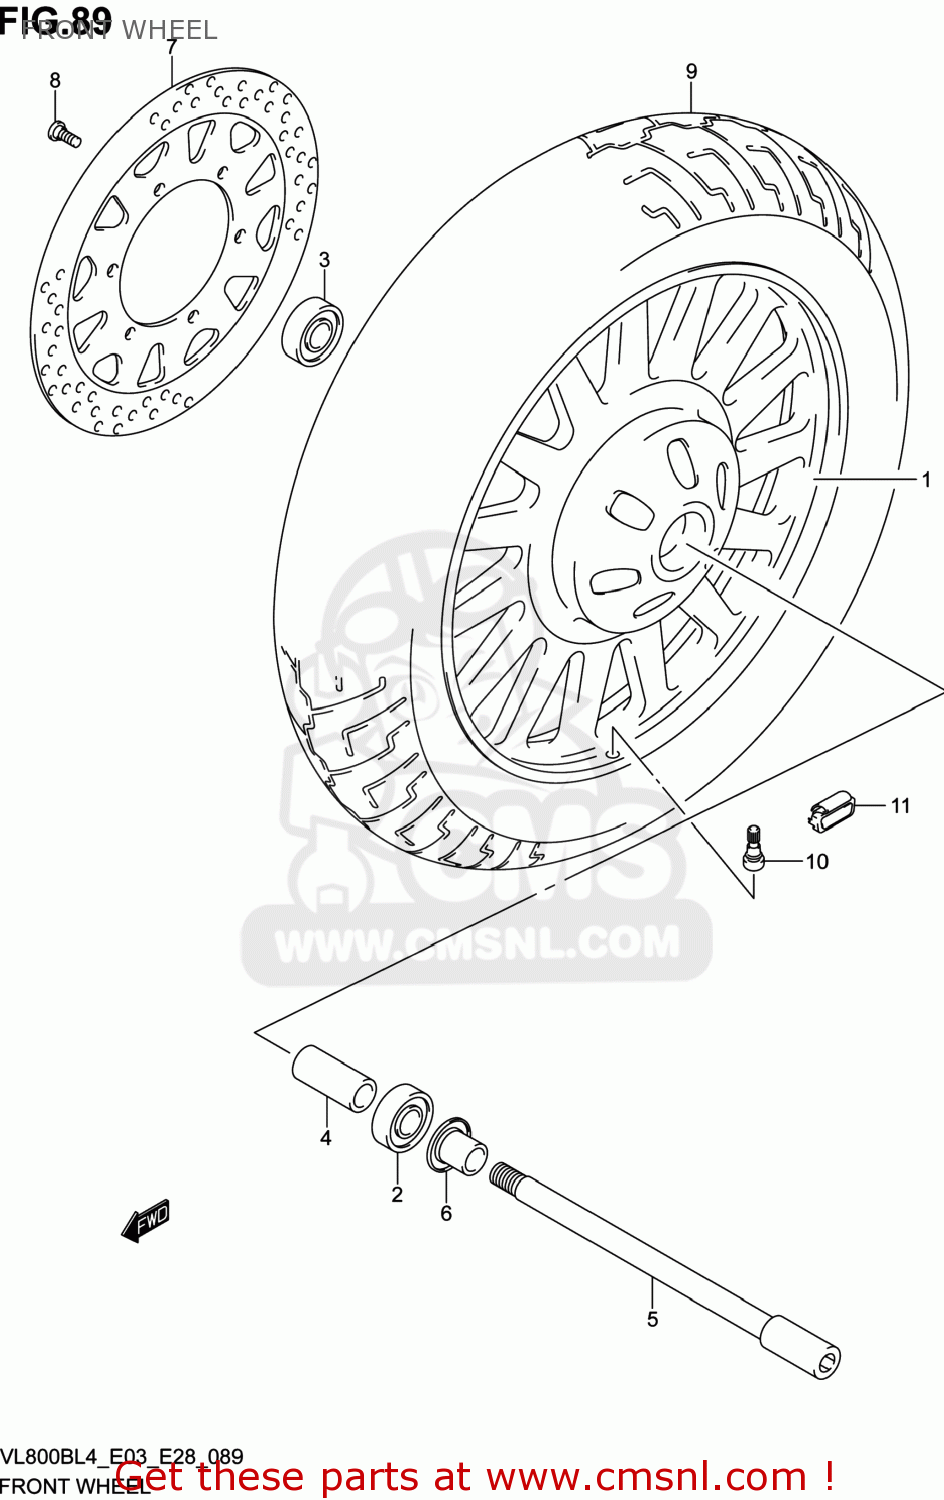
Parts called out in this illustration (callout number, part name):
1	WHEEL,FR(16M/CXMT3.00)(BLACK)
2	BEARING
3	BEARING
4	SPACER(17.5X25X102)
5	AXLE,FR
6	SPACER,FR AXLE,R
7	DISC,FRONT BRAKE
8	BOLT(8X21)
9	TIRE,FR(130/90 16M/C 67H)
10	VALVE ASSY,WHEEL RIM(TR412)
11	BALANCER,WHEEL NO.1
